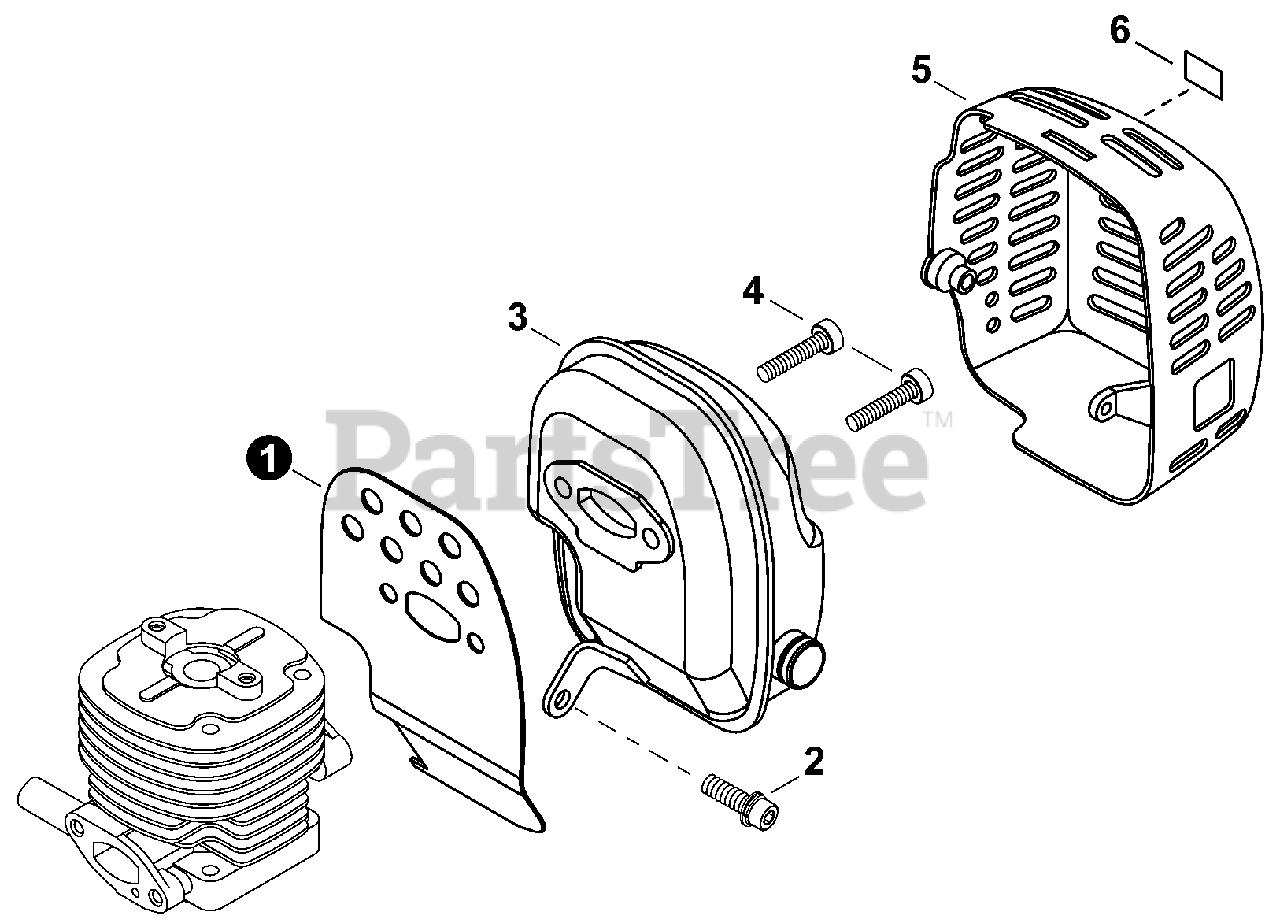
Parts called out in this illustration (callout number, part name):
1	HEAT SHIELD, EXHAUST
2	BOLT M5×12
3	MUFFLER
4	BOLT 6×25
5	COVER, MUFFLER
6	LABEL, CAUTION - HOT
